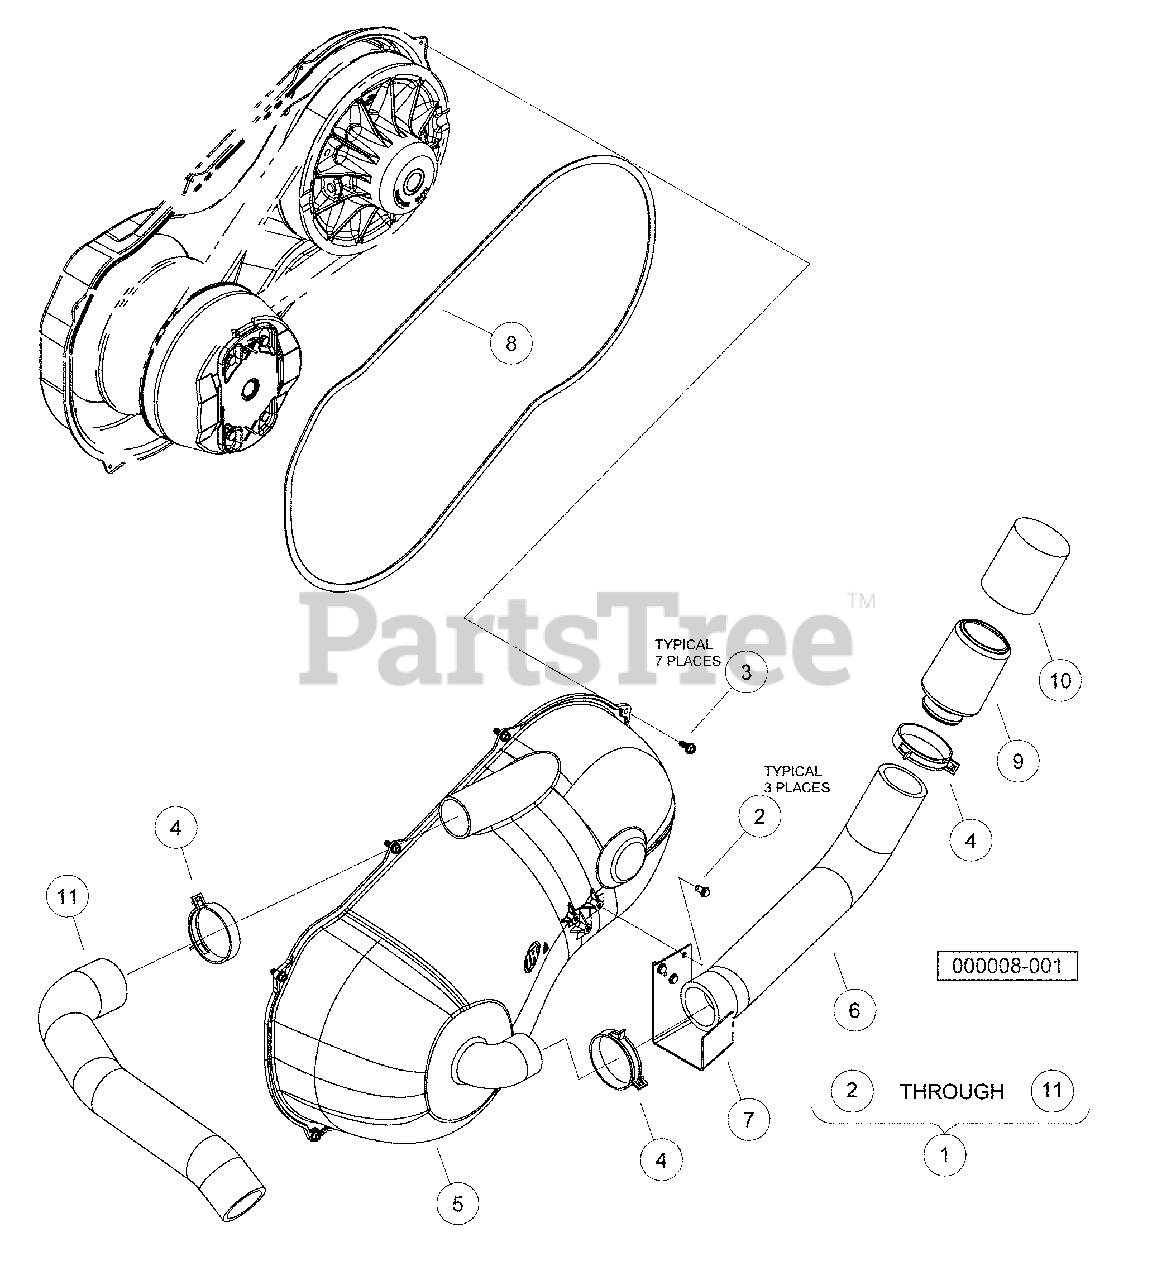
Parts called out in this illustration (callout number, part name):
1	Kit, Sealed CVT Cover
2	Screw, 1/4-15 X 1.50 Hi-lo Hex
3	Screw, M6 X 16 Tt Hx Fl Hd
4	Clamp, Hose, Ctb 64mm
5	Cover, CVT Outer
6	Hose, Inlet, Cover, CVT
7	Bracket, Inlet, Cover, CVT
8	Gasket, Cover, CVT
9	Cap, Inlet, Cover, CVT
10	Filter, Inlet, Cover, CVT
11	Hose, Outlet, Cvt
